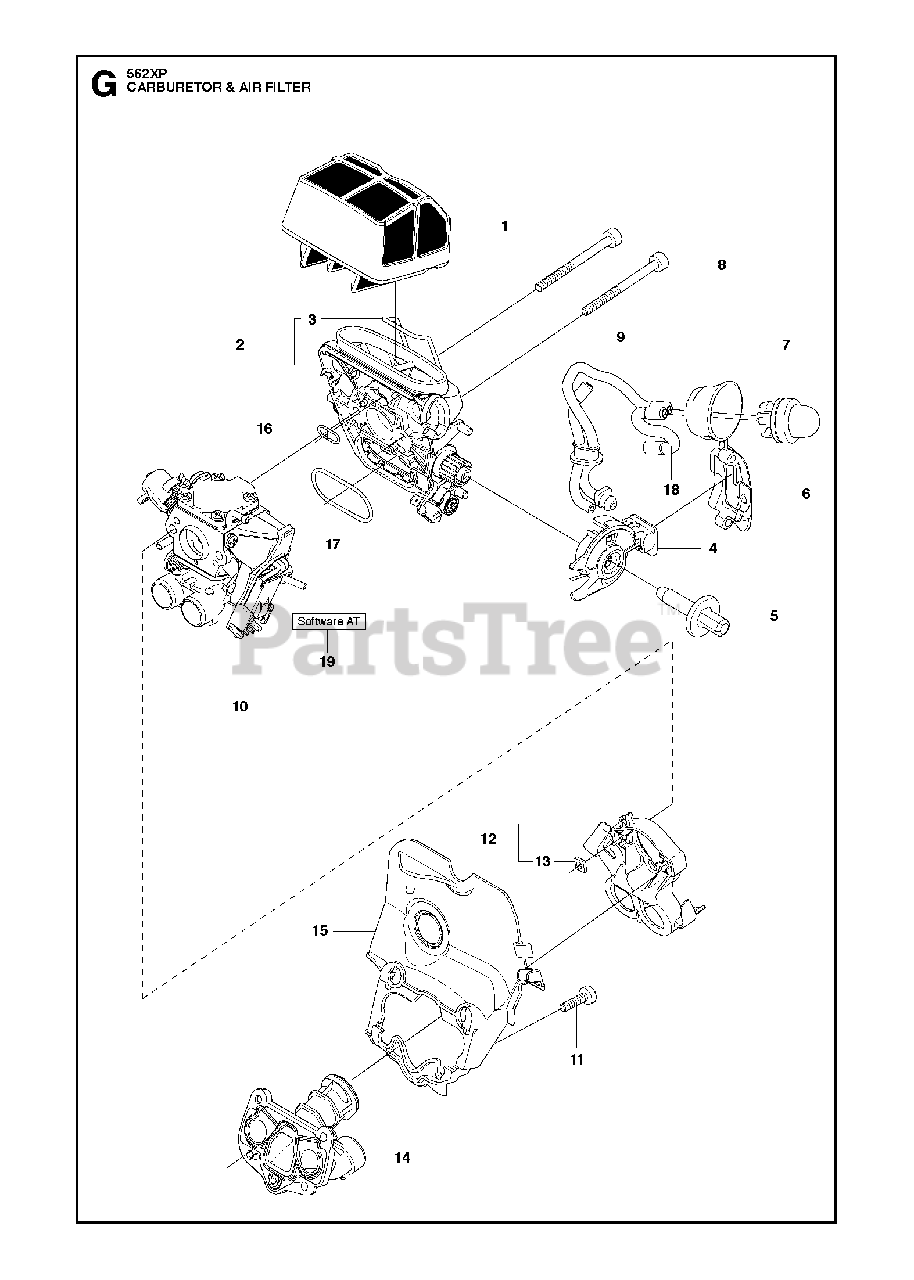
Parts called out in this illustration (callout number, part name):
1	AIR FILTER ASSY BLCK 80 MICRON
1	AIR FILTER ASSY YLLW 44 MICRON
1	AIR FILTER ASSY NATURAL FELT
2	RP FILTER HOLDER ASSY
2	FILTER HOLDER ASSY
3	SHACKLE
4	CHOKE CONTROL ASSY
7	AIR PURGE BUBBLE
9	FUEL HOSE
10	CARBURETTOR
11	SCREW IHSCM
13	NUT
14	RP INLET PIPE
15	INTERMEDIATE WALL
